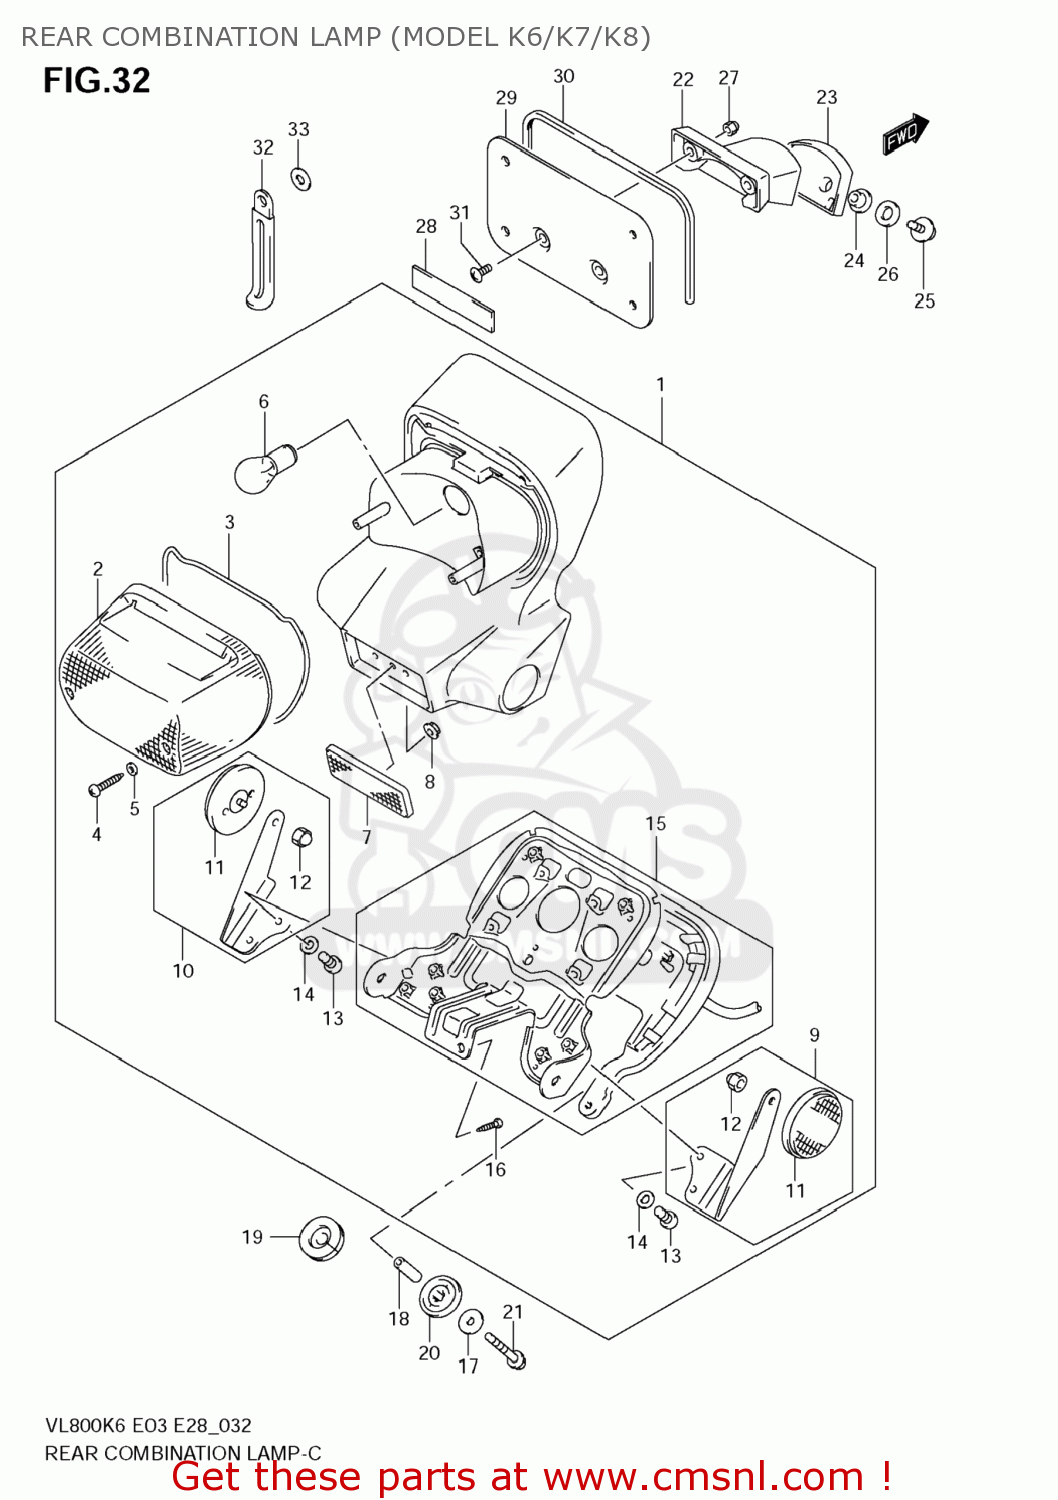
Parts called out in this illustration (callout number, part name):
1	LAMP ASSY,RR COMBINATION
2	LENS
3	GASKET,FR TURN SIGNAL LAMP (NAS)
4	SCREW
5	GASKET (NAS)
6	BULB(12V21/5W)
7	REFLECTOR ASSEMBLY,REAR
8	NUT
9	REFLEX REFLECTOR,R
10	REFLEX REFLECTOR,L
11	REFLEX REFLECTOR,RR
12	NUT
13	SCREW
14	WASHER,LOCK
15	SOCKET & CORD ASSY
16	SCREW
17	WASHER(6.5X20X1.6)
18	SPACER(6.5X9X23)
19	GROMMET
20	CUSHION
21	BOLT
22	STAY,LICENSE PLATE HOLDER
23	CUSHION,LICENSE HOLDER STAY
24	WASHER
25	BOLT
26	WASHER(6.5X18X1.6)
27	NUT
28	PROTECTOR(20X90)X1.0
29	HOLDER,LICENSE
30	MOLDING
31	SCREW
32	CLAMP(L:45)
33	WASHER(6.5X16X1.2)
